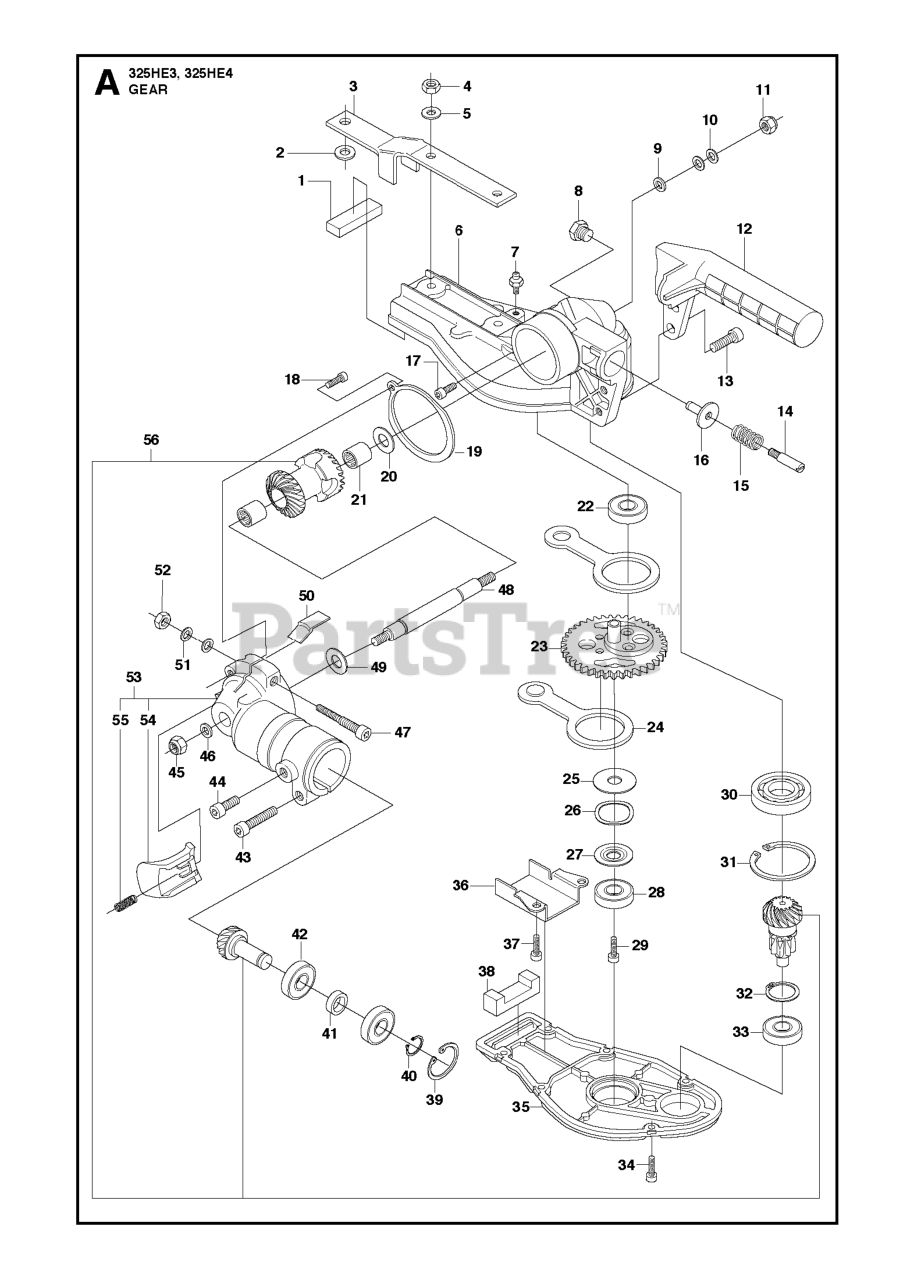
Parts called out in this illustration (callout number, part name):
1	SEALING
2	WASHER - 25X8.5X2.3
5	WASHER
6	GEAR HOUSING
7	GREASE NIPPLE
9	WASHER - M6
11	NUT FLANGE - M6
13	RP SCREW
17	SCREW MC6S 5X8
18	SCREW MC6S 5X12
21	SUPPORT BUSHING
22	BALL BEARING
24	CONNECTING ROD
28	BALL BEARING
29	SCREW MC6S 5X8
30	BALL BEARING
31	RETAINING RING SGH 35
32	RETAINING RING
33	BALL BEARING
37	SCREW MC6S 4X8
38	RP SEALING
39	RETAINING RING
40	RETAINING RING
42	BALL BEARING
45	NUT FLANGE - M6
46	WASHER - M6
52	NUT M4
53	GEAR HOUSING
